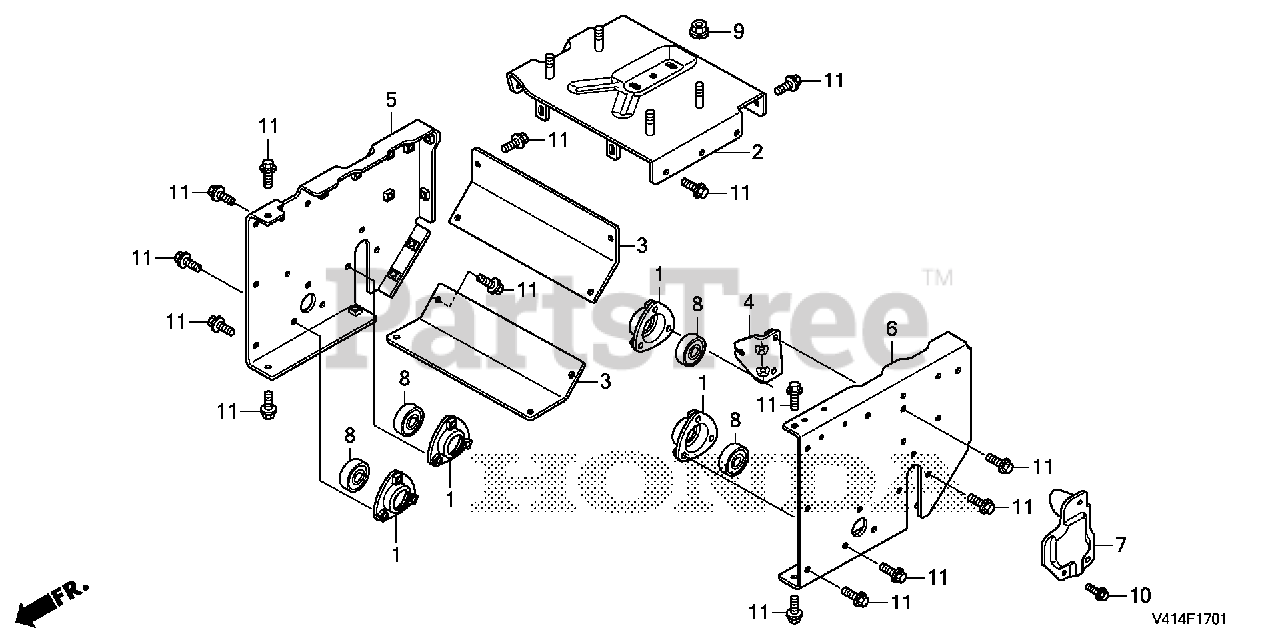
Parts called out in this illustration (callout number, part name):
1	HOLDER, BEARING
2	BED, ENGINE
3	STAY A, ENGINE BED
4	STAY, CHANGE CABLE
5	STAY, R. ENGINE BED
6	STAY, L. ENGINE BED
7	BRACKET, MOTOR COVER
8	BEARING, RADIAL BALL (6203-19.05)
9	NUT, FLANGE (10MM)
10	BOLT, FLANGE (6X12)
11	BOLT, FLANGE (8X16)
